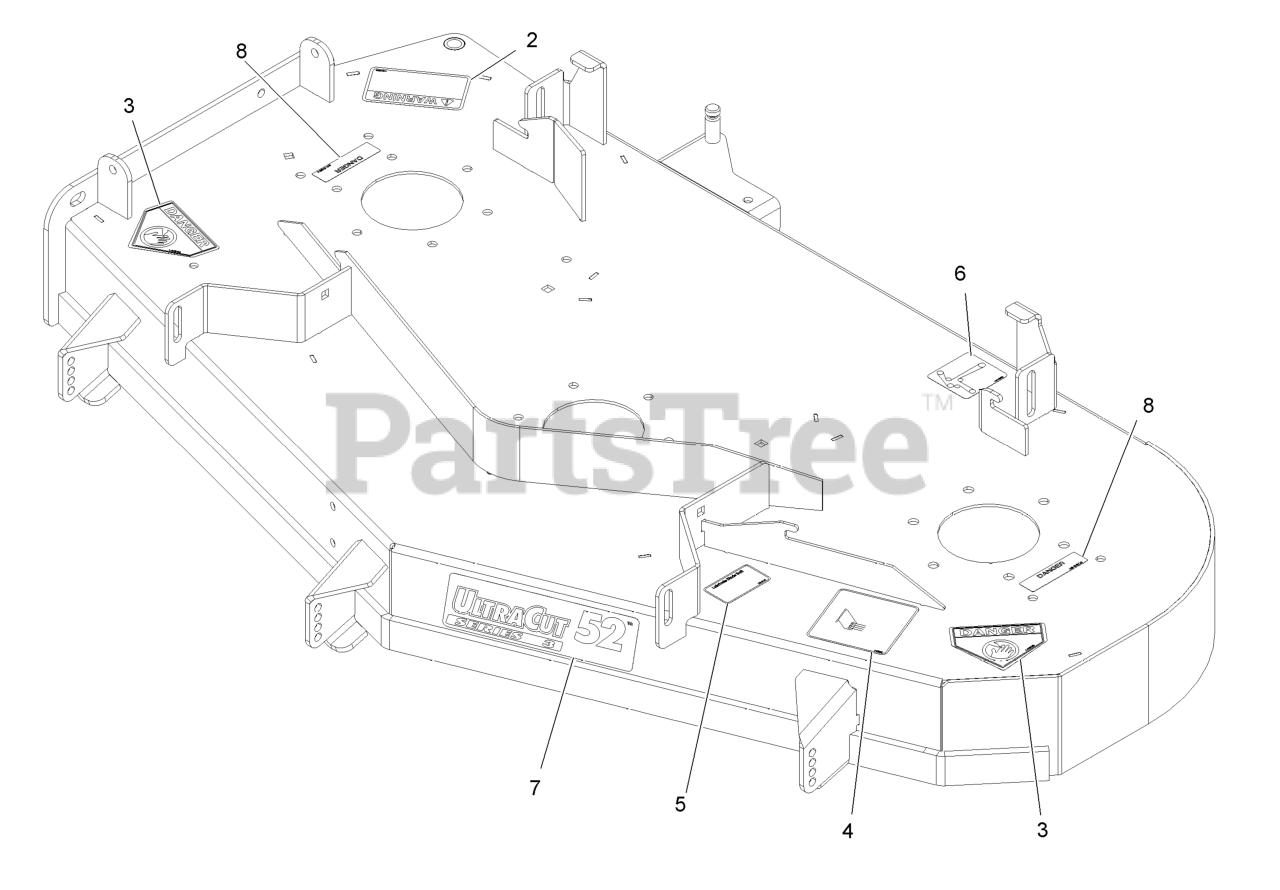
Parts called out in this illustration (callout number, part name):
2	DECAL-WARNING, DISCHARGE
3	DECAL-DANGER
4	DECAL,ANTISCALP
5	DECAL,BOLT TORQUE
6	DECAL-ROUTING, BELT
7	DECAL-ULTRACUT 52 SERIES
8	DECAL-COVER, MISSING
